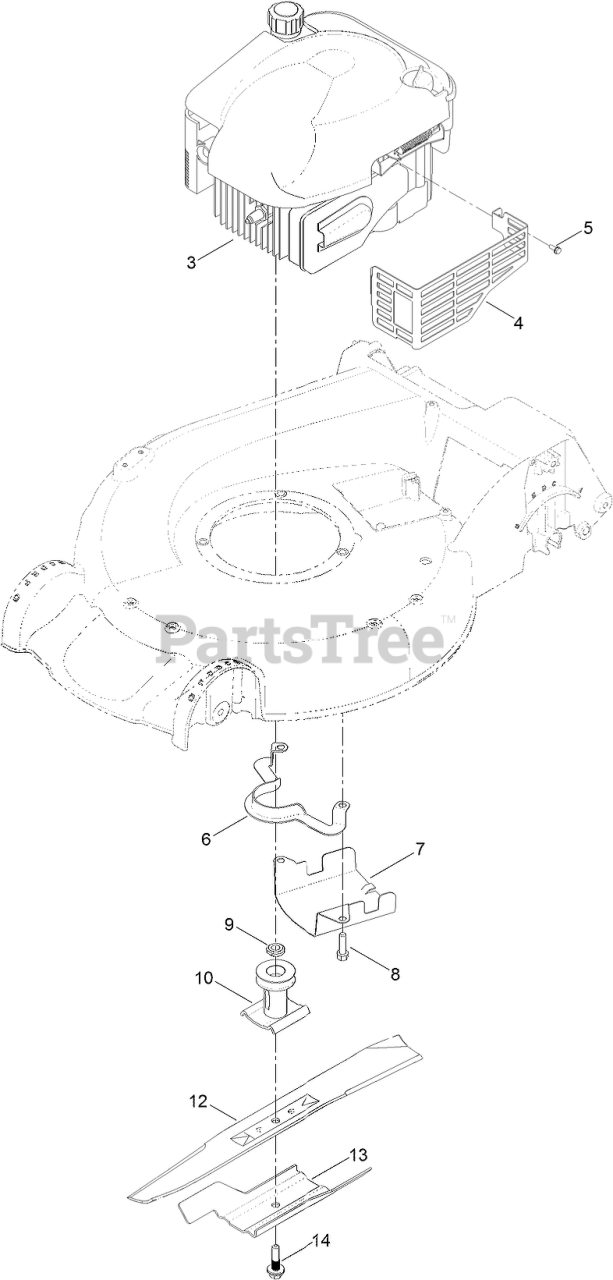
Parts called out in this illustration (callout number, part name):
4	SHIELD-MUFFLER
5	SCREW-TAPTITE
6	GUIDE-BELT
7	SHIELD-GRASS
8	SCREW-TAPTITE
9	Spacer-Driver
10	DRIVER-BLADE
12	BLADE-RECYCLING
13	Accelerator-Blade
14	BOLT-BLADE
